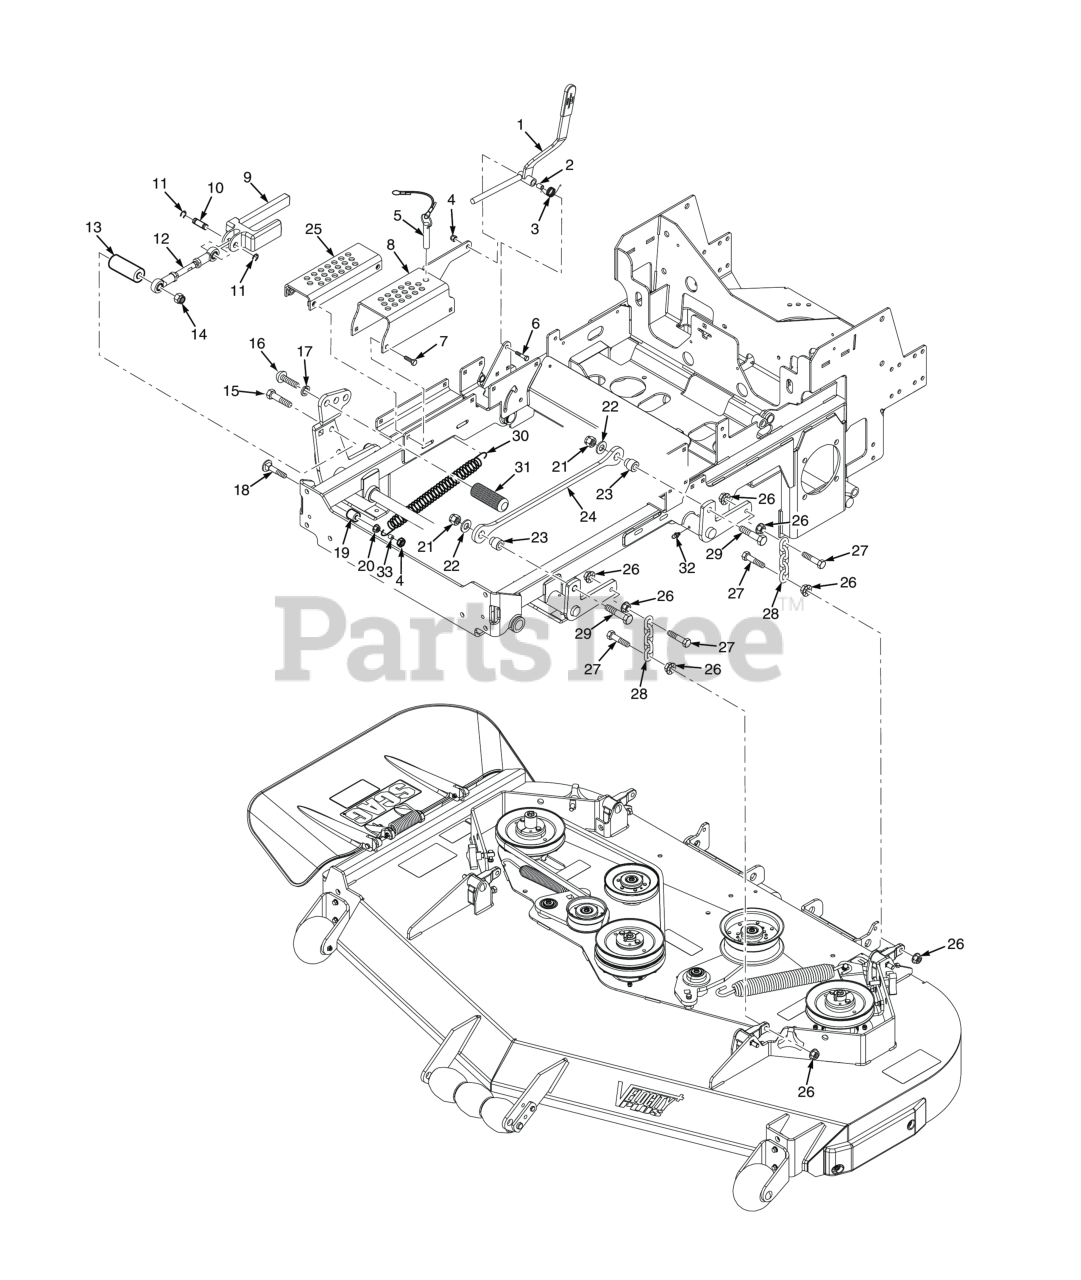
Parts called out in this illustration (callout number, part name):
1	Deck Latch Assembly (Includes Grip)
1	Grip, Deck Latch
2	Spacer, Deck Latch
3	Spring, Torsion - Lever Return
4	Bolt, Hex Head 3/8-16 x 1" Ser. Flg.
5	Lanyard, Deck Height Pin Assembly
6	Capscrew, Hex Head 3/8-16 x 2-1/2"
7	Bolt, Hex Wshr Head 5/16-18 x 1-1/4"
8	Adjustment Bracket, Cutting Height
9	Slide, Height Adjust (INCL. 10,11,12)
10	Pin, Deck Lift
11	Retaining Ring, 1/2" Ext. "E"
12	Linkage Assembly, Deck Lift
13	Spacer, Deck Lift Pedal
14	HEX LOCKNUT, ELASTIC STOP, 1/2-13
15	Bolt, Hex Head 1/2-13 x 4" (lower)
16	Capscrew, 5/8-11 x 1-1/2"
17	Lockwasher, 5/8" Spring
18	Carriage Bolt, 3/8-16 x 2-1/2"
19	Yoke, Front Caster Wheel
20	NUT, 3/8-16 SERRATED FLANGE HEX HEAD
21	HEX LOCKNUT, ELASTIC STOP, 1/2-13
22	Flat Washer, 1/2 (.562 x 1.375 x .109)
23	Pivot, Deck Link
24	Link, Decklift (black)
25	Adjustment Bracket, Lower Cut Height
26	NUT, 3/8-16 SERRATED FLANGE HEX HEAD
27	Bolt, Hex Head, 3/8-16 x 1-1/2"
28	Chain, Deck Lift
29	Bolt, Hex Head 1/2-13 x 2-1/4"
30	Spring, Decklift
31	Foot Pedal, Height Adjustment
32	GREASE FITTING, STR. 1/4-28 SELF TAP.
33	Spacer, Deck Assist
